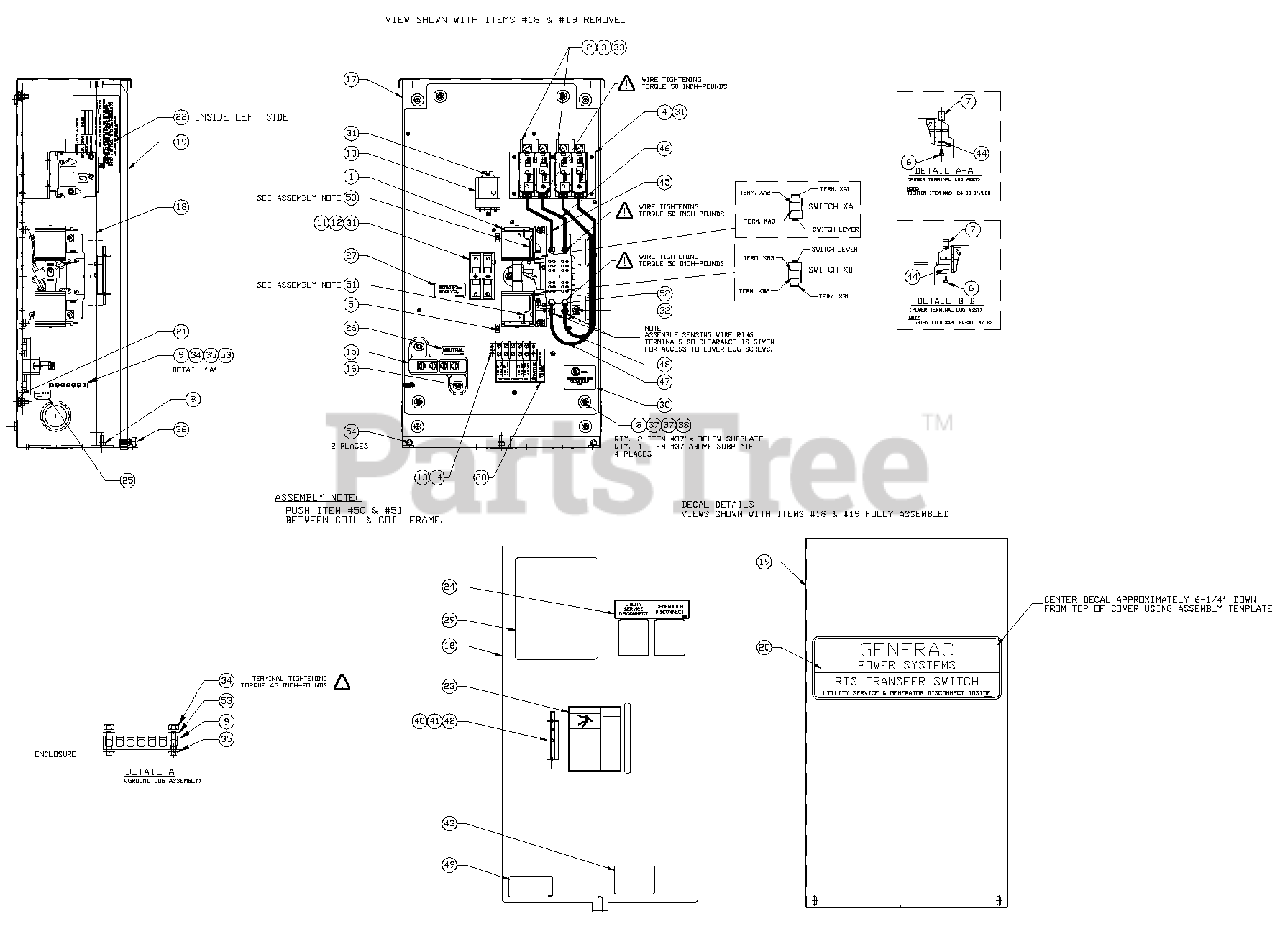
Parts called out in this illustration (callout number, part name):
1	TR SW-HSB 100A 2P 250V
2	CB 100A 2P BACK MNT SIEMENS
3	C/BKR MOUNTING BRACKET
4	RISER 100 AMP CIRCUIT BREAKERS
5	HOLDER CABLE TIE
6	SCREW PPHMS 10-32 X 3/8""
7	LUG SLDLSS 1/0-#14 X 9/16 AL/CU
8	NUT HEX M6 X 1.0 G8 YEL CHR
9	GROUND BAR (5) 4-14 AWG CONN
10	RELAY PNL 12VDC DPDT
11	FUSEBLOCK 30A 600V 2 POLE
12	FUSE 5A X BUSS HLDR73591
13	BLOCK, TERM 20A 5 X 6
14	RIVET POP .156 X .67
15	ASSY NEUTRAL BLOCK 100A
16	SCREW HHTT M6-1.0 X 12 MM
17	WELDMENT TRANSFER SWITCH
18	COVER INSIDE TRANSFER SWITCH ENCL
19	COVER TRANSFER SWITCH
20	DECAL TRANSFER SWITCH RTS SE
21	SUBPLT XFER SW HSB
22	DECAL DATA XFER SW 100A 240V
23	DECAL MANUAL OPERATING HANDLE
24	DECAL UTILITY/GENERATOR DISCONNECT
25	DECAL GROUNDING LUG
26	DECAL NEUTRAL
27	DECAL FUSE REPLACEMENT
28	DECAL TERMINAL STRIP
29	DECAL TEST SEQUENCE
30	DECAL UL LISTED HSB
31	SCREW HHTT M4-.7 X 8 BP
32	SCREW HHTT M5-0.8 X 10 BP
33	SCREW HHTT M5-0.8 X 8 BP
34	NUT HEX LOCK M4-0.7 SS NYL INS
35	WASHER SHAKEPROOF EXT #8 STEEL
36	THUMB SCREW 1/4-20x1/2
37	WASHER FLAT 1/4-M6 ZINC
38	WASHER LOCK M6-1/4
40	BRACKET ARM EXTENDER
41	SCREW HWHS #6-25 X 3/8 ZNC
42	ARM EXTENDER PIN
43	DECAL TERMINAL SHOCK
44	WASHER LOCK # 10
45	WIRE ASM 2AWG 100A 2-P T/S N1A
46	WIRE ASM 2AWG 100A 2-P T/S N2A
47	WIRE ASM 2AWG 100A 2-P T/S E1A
48	WIRE ASM 2AWG 100A 2-P T/S E2A
49	DECAL LIVE-CIRCUIT
52	WIRE-E1
53	WASHER FLAT M4
54	NUT TRIC 1/4-20 X .525
